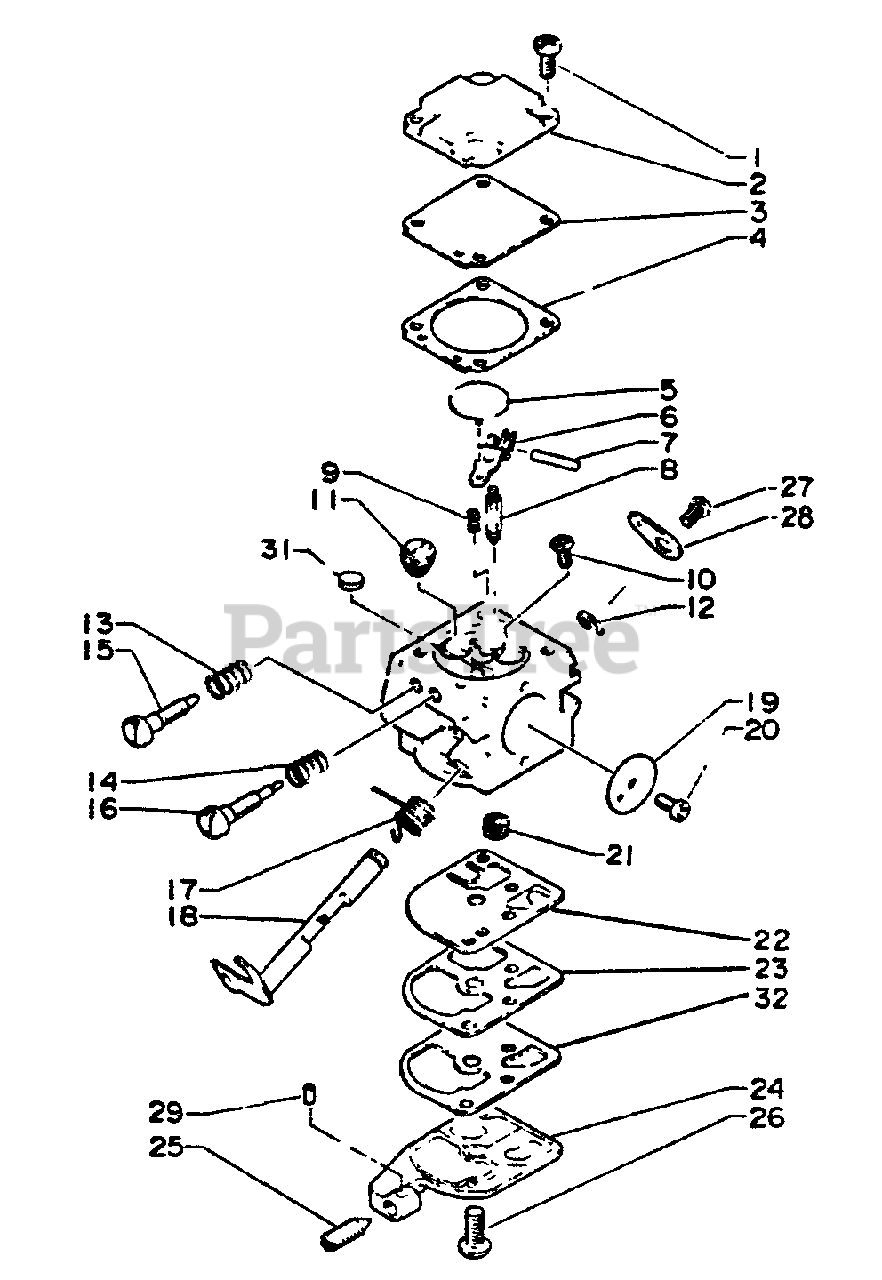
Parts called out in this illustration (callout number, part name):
1	SCREW
2	COVER, DIAPHRAGM
3	DIAPHRAGM
4	GASKET, METERING
5	DISK
6	LEVER, METERING
7	PIN, METERING LEVER
9	SPRING, METERING LEVER
11	NOZZLE, CHECK VALVE
13	SPRING
15	NEEDLE, HIGH SPEED
16	NEEDLE, IDLE
17	SPRING, THROTTLE RETURN
18	SHAFT, THROTTLE
19	VALVE, THROTTLE
20	SCREW
21	STRAINER
24	BASE, PUMP
25	SCREW, IDLE ADJUST
28	LEVER, THROTTLE
29	PIECE, FRICTION
31	PLUG, WELCH
